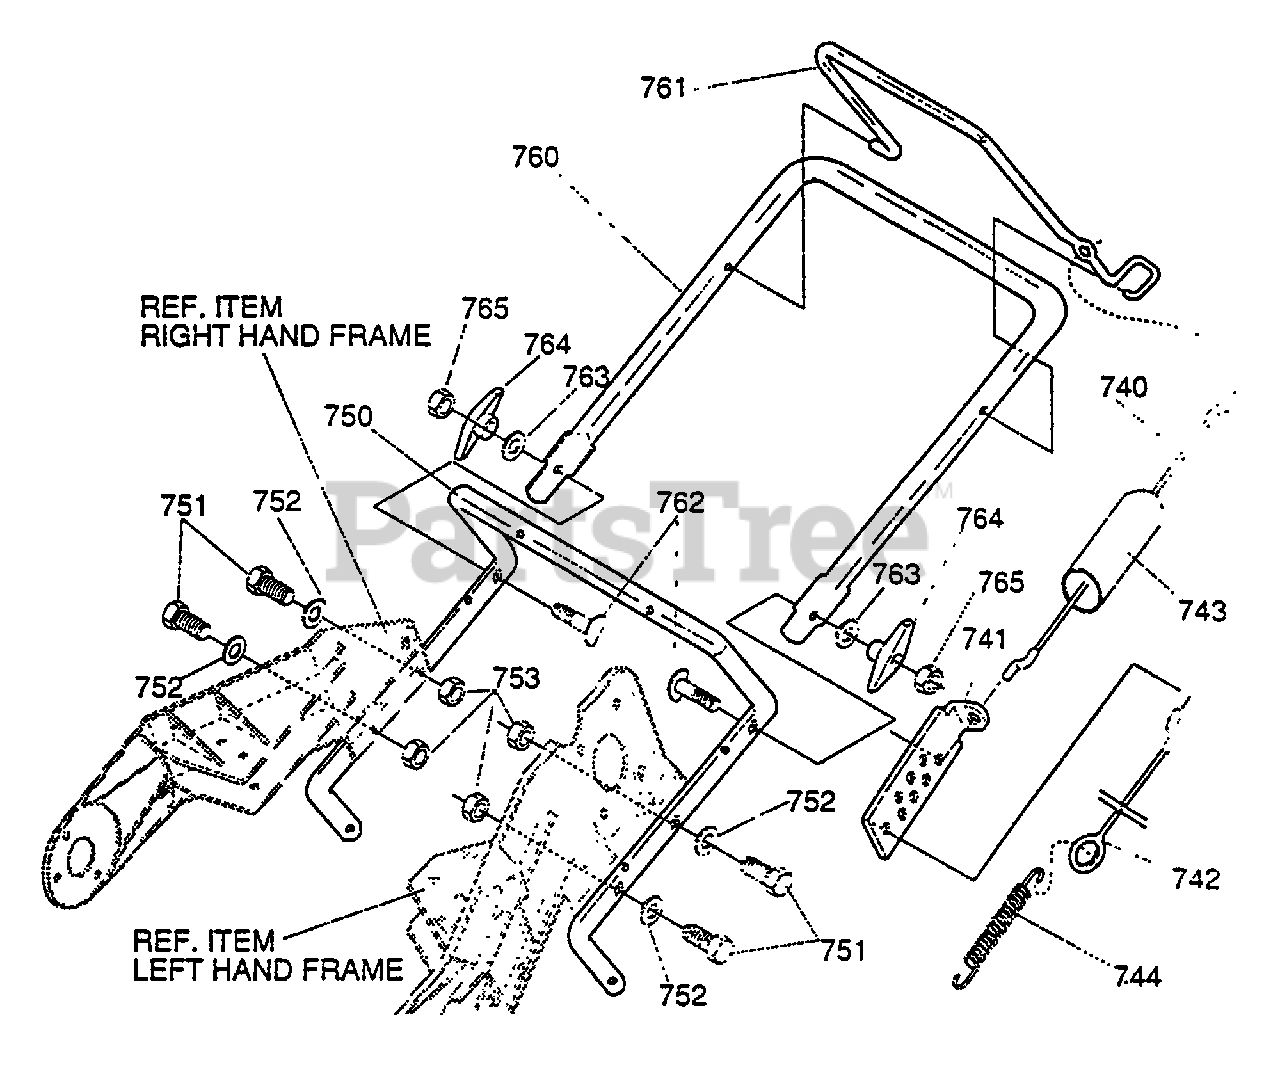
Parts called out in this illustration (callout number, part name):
740	CABLE, UPPER CONTROL
741	BRKT, CABLE ADJ
742	CABLE, LOWER CONTROL
743	BOOT, CLUTCH SPRING
744	SPRING, EXT
750	HDL, LOWER
751	SCREW, 1/4-20 X 1.25
752	FLATWASHER .281 X .63 X .065
753	NUT, 1/4-20 REG HEX CTRLK
760	HANDLE, UPPER
761	BAIL, CONTROL
762	BOLT, 5/16-18 X 1.75
763	WASHER, FORM
764	KNOB, T W/NUT
765	NUT, 5/16-18 REG HEX
